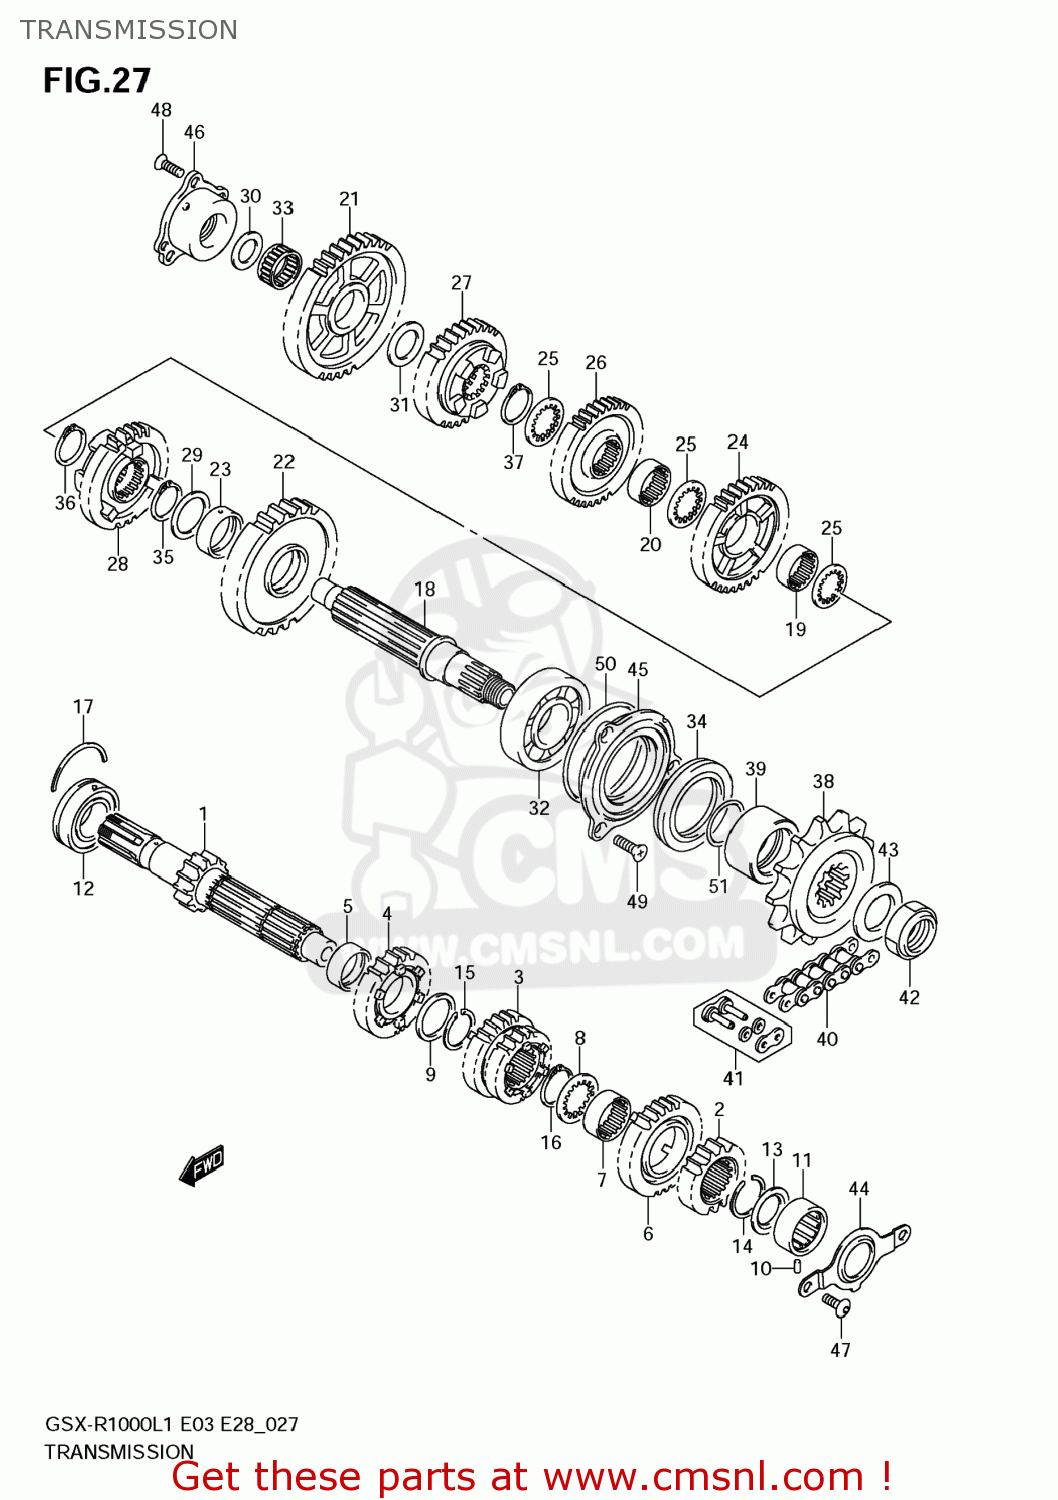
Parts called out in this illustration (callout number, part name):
1	SHAFT,COUNTER
2	GEAR,2ND DRIVE
3	GEAR,3RD & 4TH DRIVE
4	GEAR,5TH DRIVE
5	BUSH,5TH DRIVE GEAR
6	GEAR,6TH DRIVE
7	BUSH,6TH DRIVE GEAR
8	WASHER,LOCK
9	WASHER(27X36X1)
10	PIN
11	BEARING(20X34X16)
12	BEARING(25X52X20.6)
13	SEAL,OIL(20X31.2X2.7)
14	CIRCLIP
15	CIRCLIP
16	CIRCLIP
17	C RING
18	SHAFT,DRIVE
19	BUSH,3RD DRIVEN GEAR
20	BUSH,3RD DRIVEN GEAR
21	GEAR,1ST DRIVEN
22	GEAR,2ND DRIVEN
23	BUSH,2ND DRIVEN GEAR
24	TANDWIEL 3E V
25	WASHER,3RD & 4TH DRIVEN GEAR
26	TANDWIEL.4E V
27	GEAR,5TH DRIVEN
28	GEAR,6TH DRIVEN
29	SHIM(30X40X1)
30	SHIM(22X34X1)
31	SHIM(24X34X1)
32	BEARING(30X62X23.8)
33	BEARING(24X28X13)
34	SEAL,OIL(38X56X7)
35	CIRCLIP
36	CIRCLIP
37	CIRCLIP
38	SPROCKET,ENGINE
39	SPACER,ENGINE SPROCKET
40	CHAIN,DRIVE
41	JOINT SET,DRIVE CHAIN
42	NUT
43	SHIM(27X42X1.5)
44	RETAINER,CL PUSH ROD OIL SEAL
45	RETAINER,DRIVE SHAFT BEARING,L
46	HOUSING,DRIVE SHAFT SET
47	SCREW(6X13)
48	SCREW(6X20)
49	SCREW(6X20)
50	O RING(D:1.9,ID:61.5)
51	O RING(D:2.4,ID:26.2)
